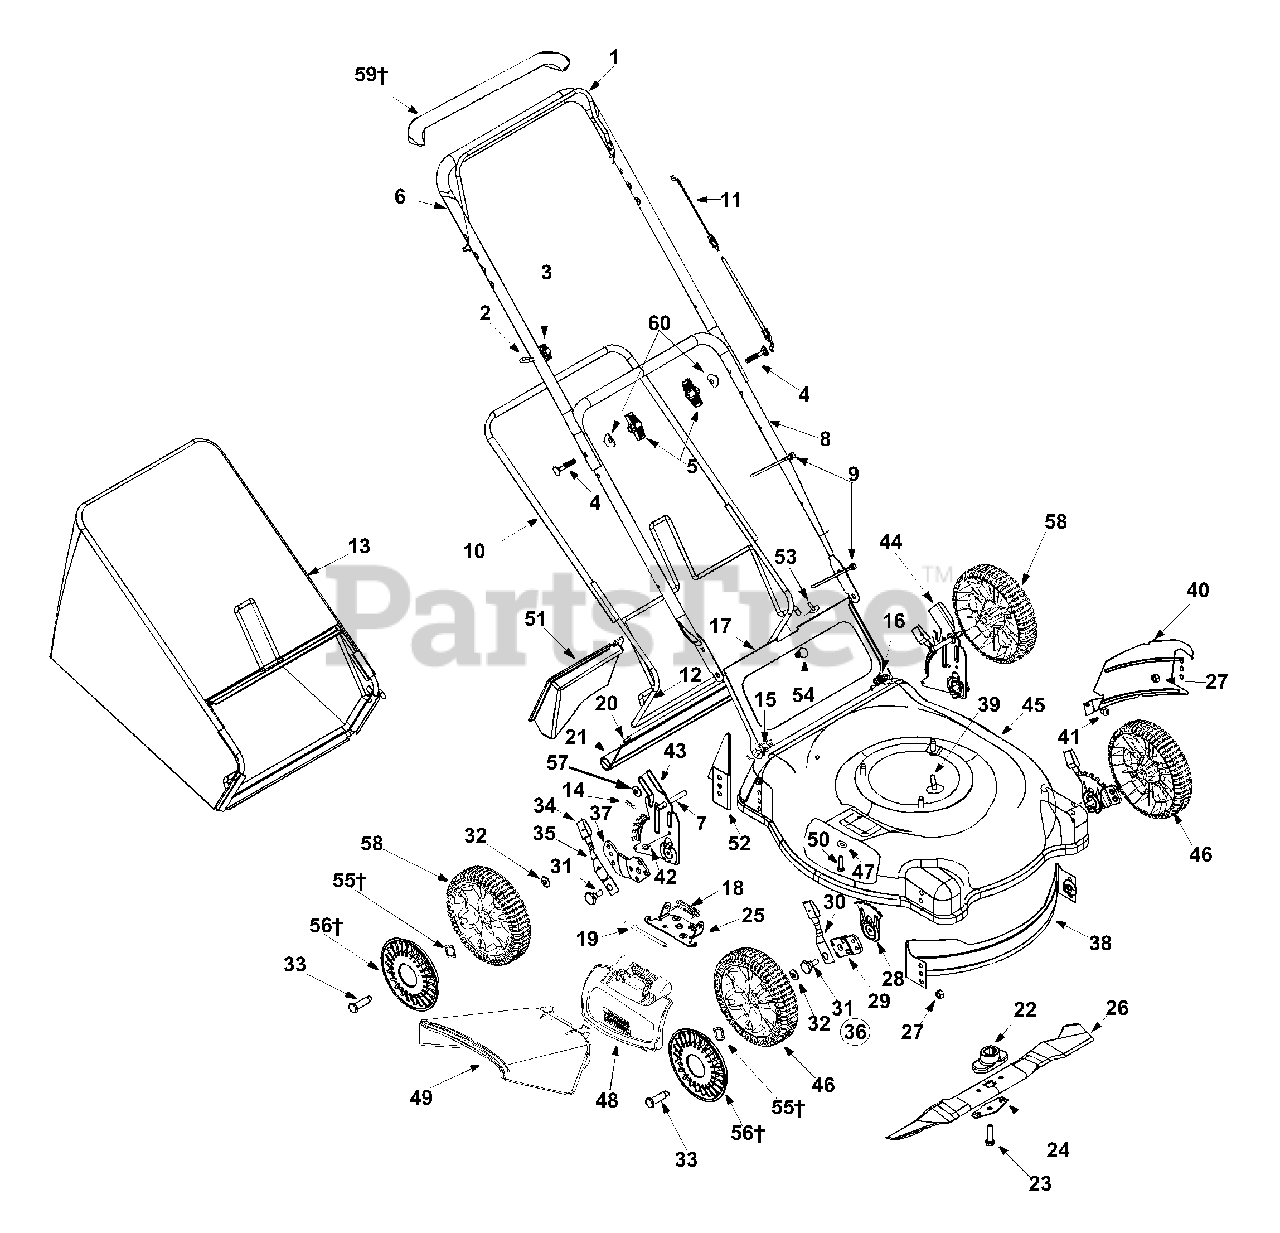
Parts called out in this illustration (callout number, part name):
2	Rope Guide
3	Handle Knob 1/4-20 Thd.
4	Curved Hd. Bolt 5/16-18 x 2"
5	Hand Knob
7	Weld Pin
9	Cable Tie
11	Control Cable - 53"
14	Int. Cotter Pin 5/16" Dia.
15	Door Spring - R.H.
16	Door Spring - L.H.
19	Hinge Pin
20	Wire Rod
21	Rear Flap
22	Blade Adapter w/Star
23	Hex Bolt 3/8-24 x 1.5" Lg.
24	Blade Bell Support
25	Deflector Chute Adapter
26	21" Mulching Blade w/Star
27	Flange Nut 3/8-16 Thd.
28	Height Adj. Plate
30	Front Spring Lever
31	Shld. Bolt.5" Dia. x.357"
32	Bell Washer.38" I.D. x.88" O.D.
33	Axle Bolt
34	Spring Lever Knob
35	Rear Spring Lever
36	Height Adj. Assy. Comp. - RH
37	Pivot Bar R.H.
41	Torx Mach AB-Tap Scr. 1/4 x.62"
42	Hex Ind Wash. Scr. 1/4-14:.625
47	Bell Washer 1/4" I.D.
48	Hinged Mulching Plug
49	Chute Deflector: Side Discharge
50	Hex Hd Self-Tp Scr. 1/4-20 x.5"
51	Mulching Baffle Plug
53	Truss Scr. #10-24 x.38" Lg.
55	Wave Washer
56	Hub-Cap- Radial Spoke Gray
57	Flat Washer
58	Rr. Wheel w/Bearings Black Link
59	Bail Cover
60	Shoulder Washer
